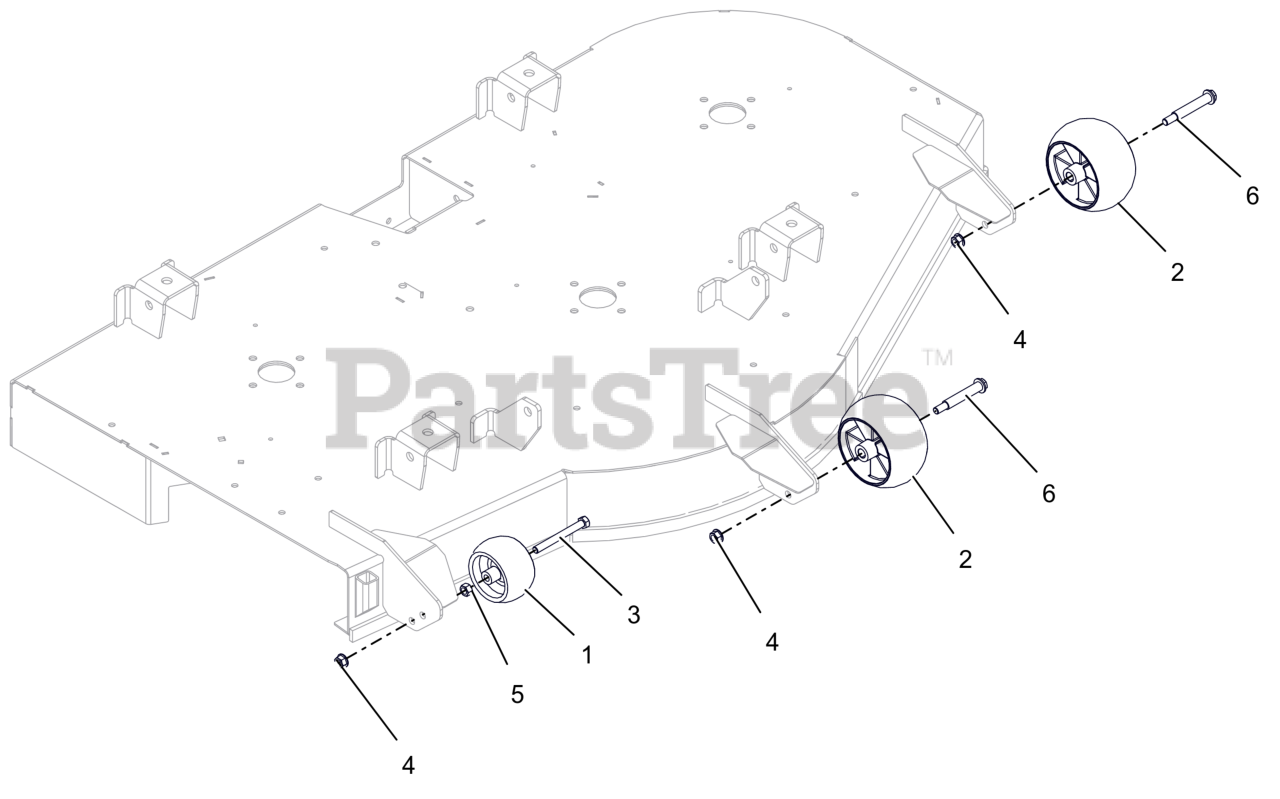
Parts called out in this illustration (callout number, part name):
2	ANTI-SCALP WHEEL - 5X OS
3	BLT, HEX .38-16X3.50 G5 ZCC
4	NUT-LK-CTR-FLG .375-16 GF ZCC
5	NUT-STD .375-16 G2 ZCC
6	BLT-SHLDR .38-16X2.50 HWH G5
